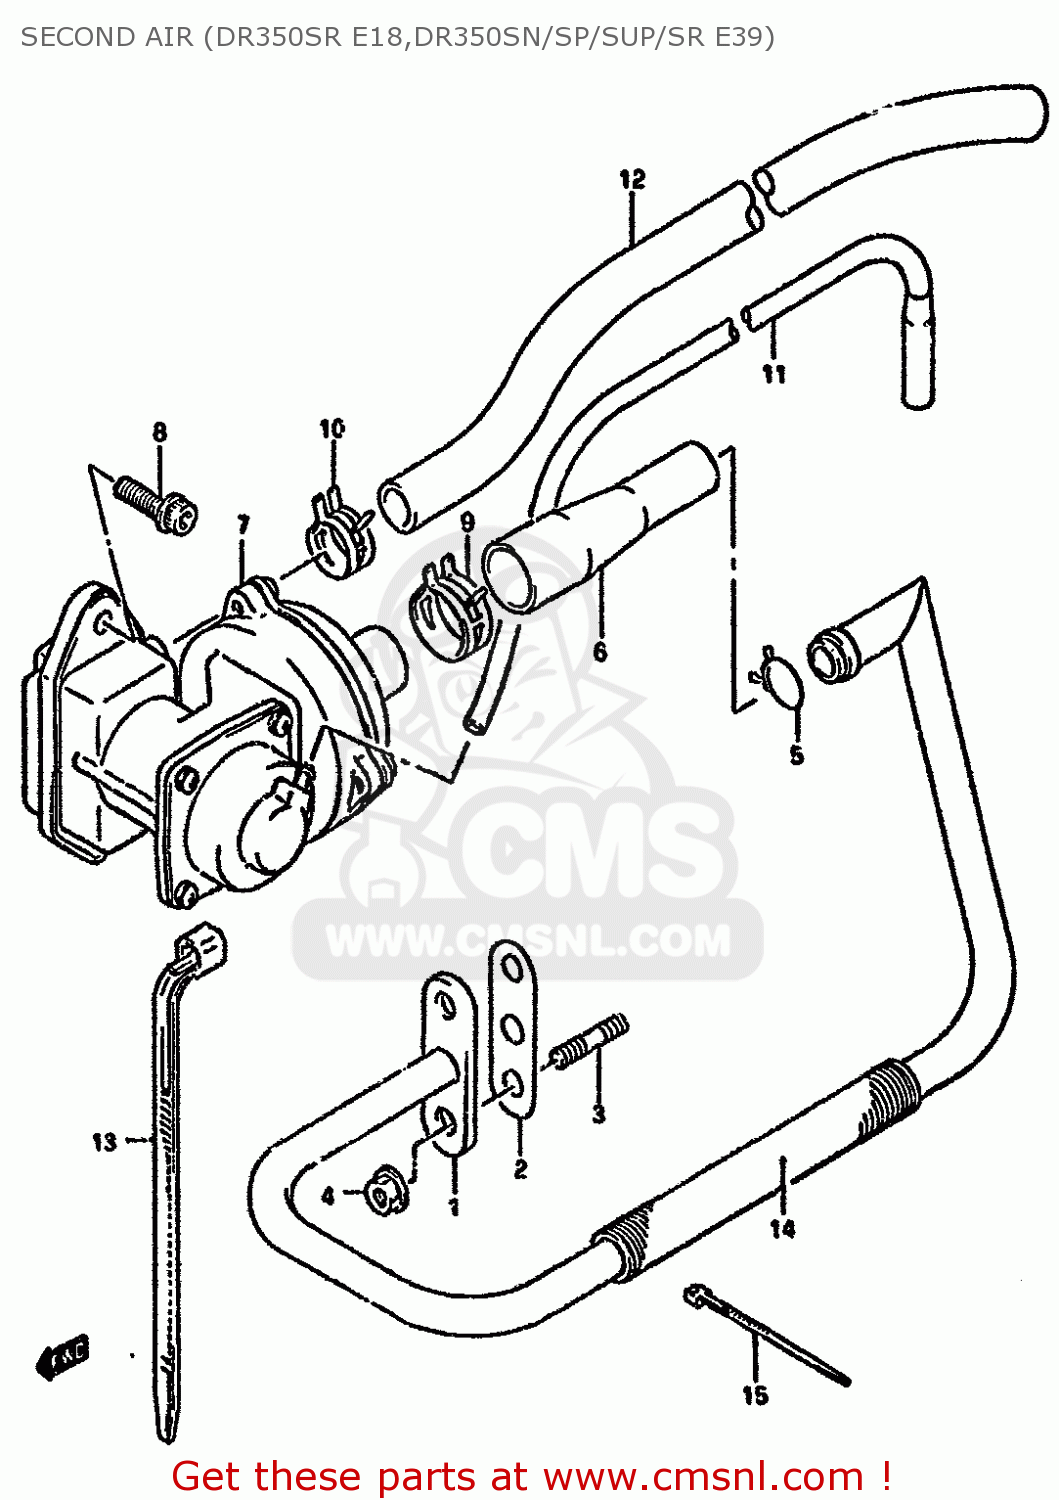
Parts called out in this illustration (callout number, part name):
1	PIPE,2ND AIR
2	GASKET,2ND AIR (NAS)
3	STUD 6X16
4	NUT
5	CLIP
6	HOSE, 2ND AIR
7	VALVE ASSY,2ND AIR REED
8	BOLT
9	CLIP
10	CLIP
11	HOSE(4X7X600)
12	HOSE(12X16X600)
13	CLAMP(L:165)
14	PROTECTOR, 2WD AIR PIPE
15	CLAMP(L:100)
16	CLIP
17	CLAMP(L:55)
18	PLUG(10X12)
19	CLAMP(L:165)
20	PROTECTOR,2ND AIR PIPE
21	CLAMP
22	CLAMP(L:125)
